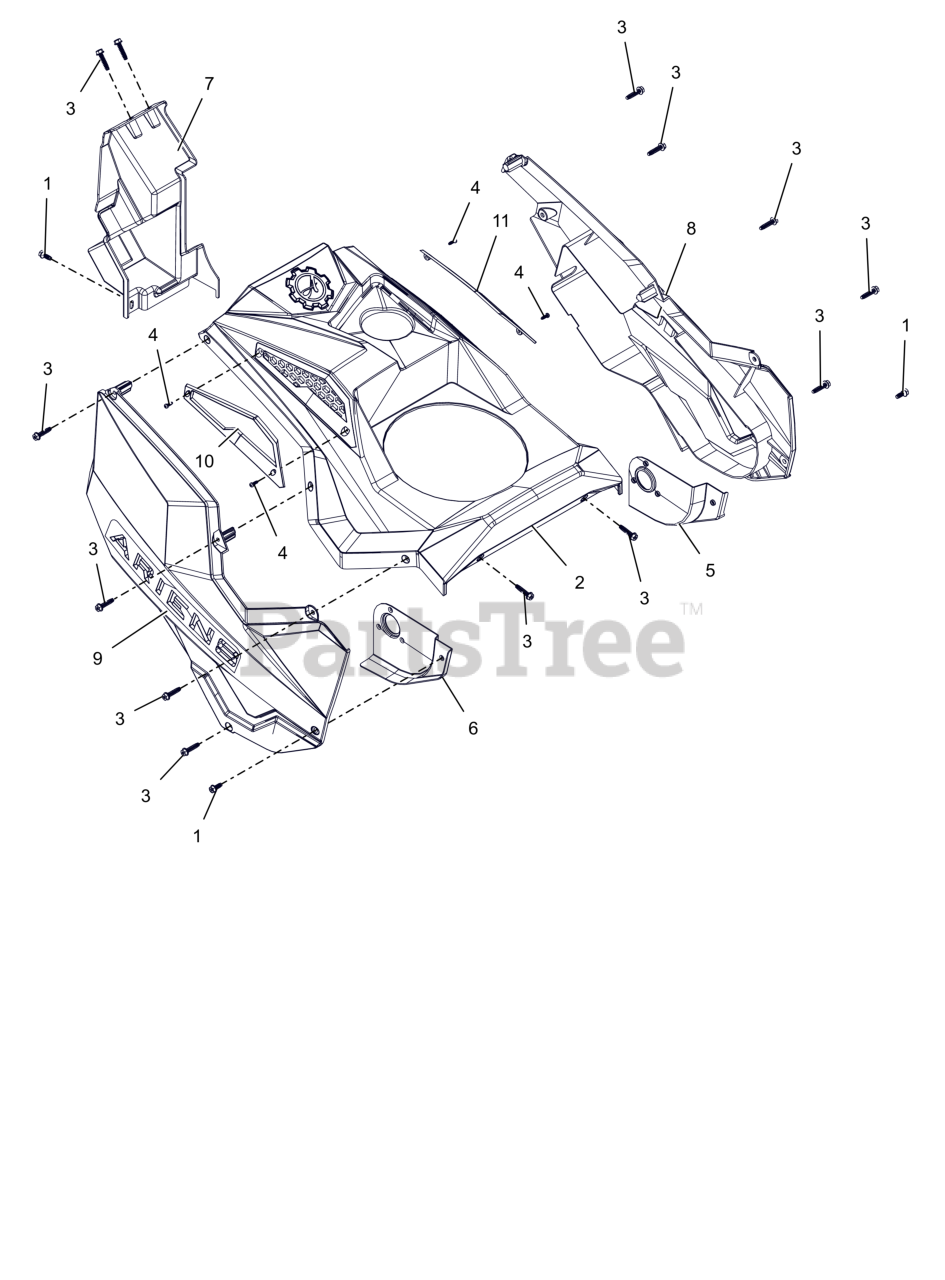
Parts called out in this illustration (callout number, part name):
1	1/4-20 X 5/8 TAPTITE
2	KIT, TOP COVER W/DECALS
3	1/4"-10x1.12 TRI-LOBE SCREW
4	M4x12 DELTA PT TRS SCREW
5	STAMPING, INNER LH
6	STAMPING, INNER - RH
7	PANEL, REAR
8	SHROUD, LEFT
9	SHROUD, RIGHT
10	TRIM, RH VENT
11	TRIM, LH VENT
